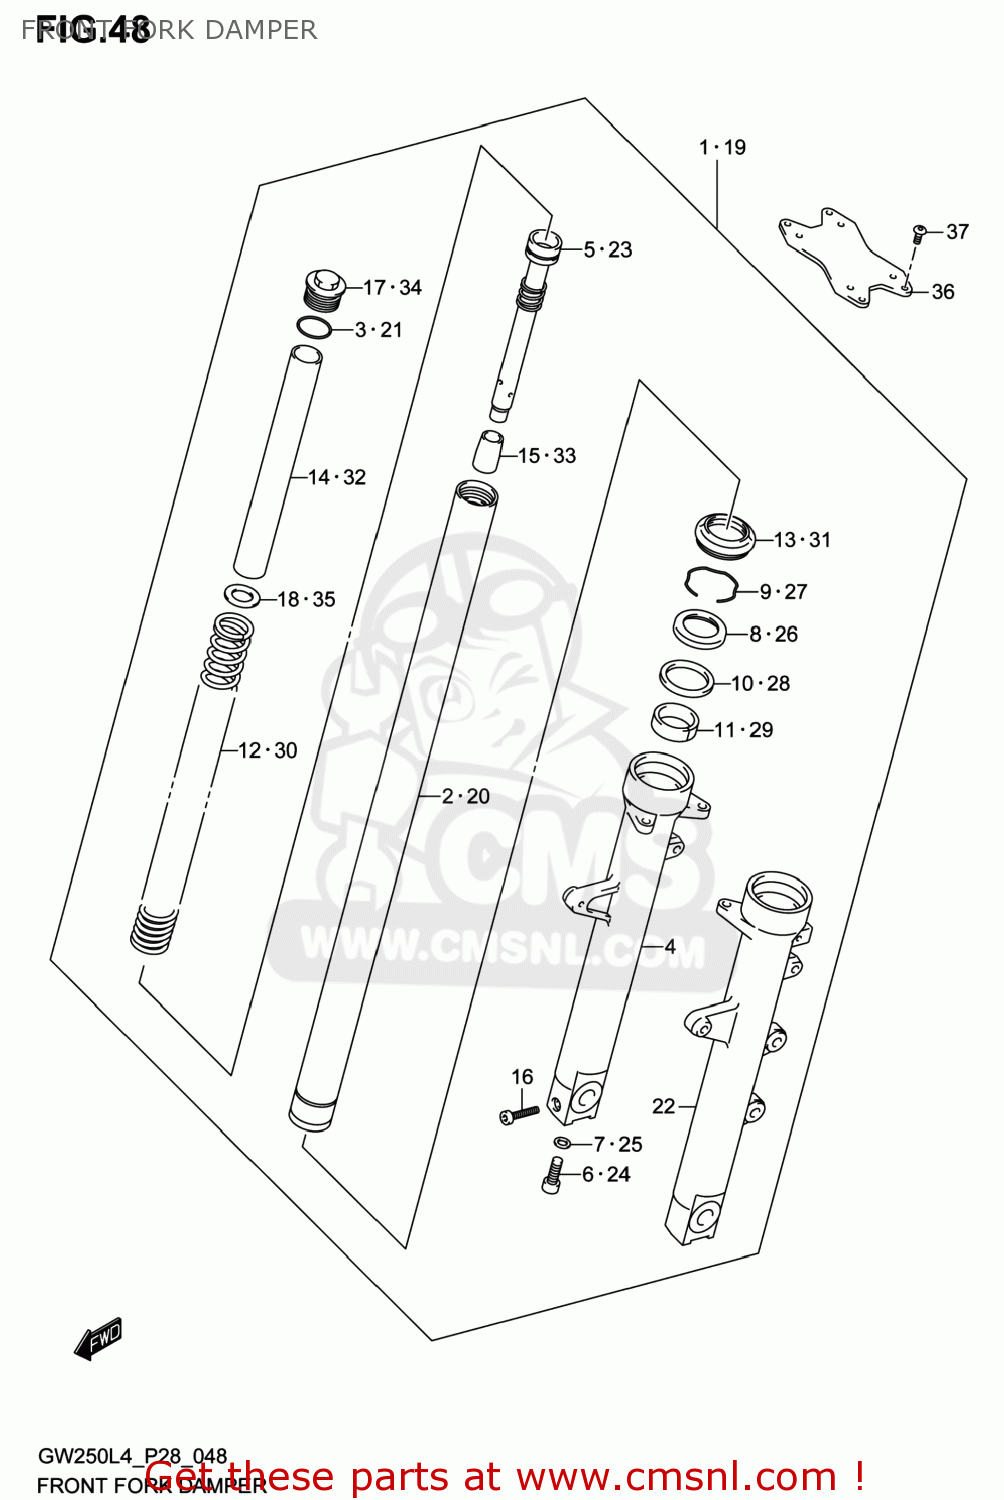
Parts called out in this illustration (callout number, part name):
1	DAMPER ASSY,FR FORK,R
2	TUBE,INNER
3	O RING
4	TUBE,OUTER,R
5	CYLINDER
6	BOLT
7	GASKET (NAS)
8	SEAL,OIL
9	RING,STOPPER
10	WASHER
11	METAL,SLIDE
12	SPRING
13	SEAL,DUST
14	SPACER
15	PIECE,OIL LOCK
16	BOLT
17	CAP
18	WASHER
19	DAMPER ASSY,FR FORK,L
20	TUBE,INNER
21	O RING
22	TUBE,OUTER,L
23	CYLINDER
24	BOLT
25	GASKET (NAS)
26	SEAL,OIL
27	RING,STOPPER
28	WASHER
29	METAL,SLIDE
30	SPRING
31	SEAL,DUST
32	SPACER
33	PIECE,OIL LOCK
34	CAP
35	WASHER
36	STABILIZER,FR
37	SCREW(6X16)
